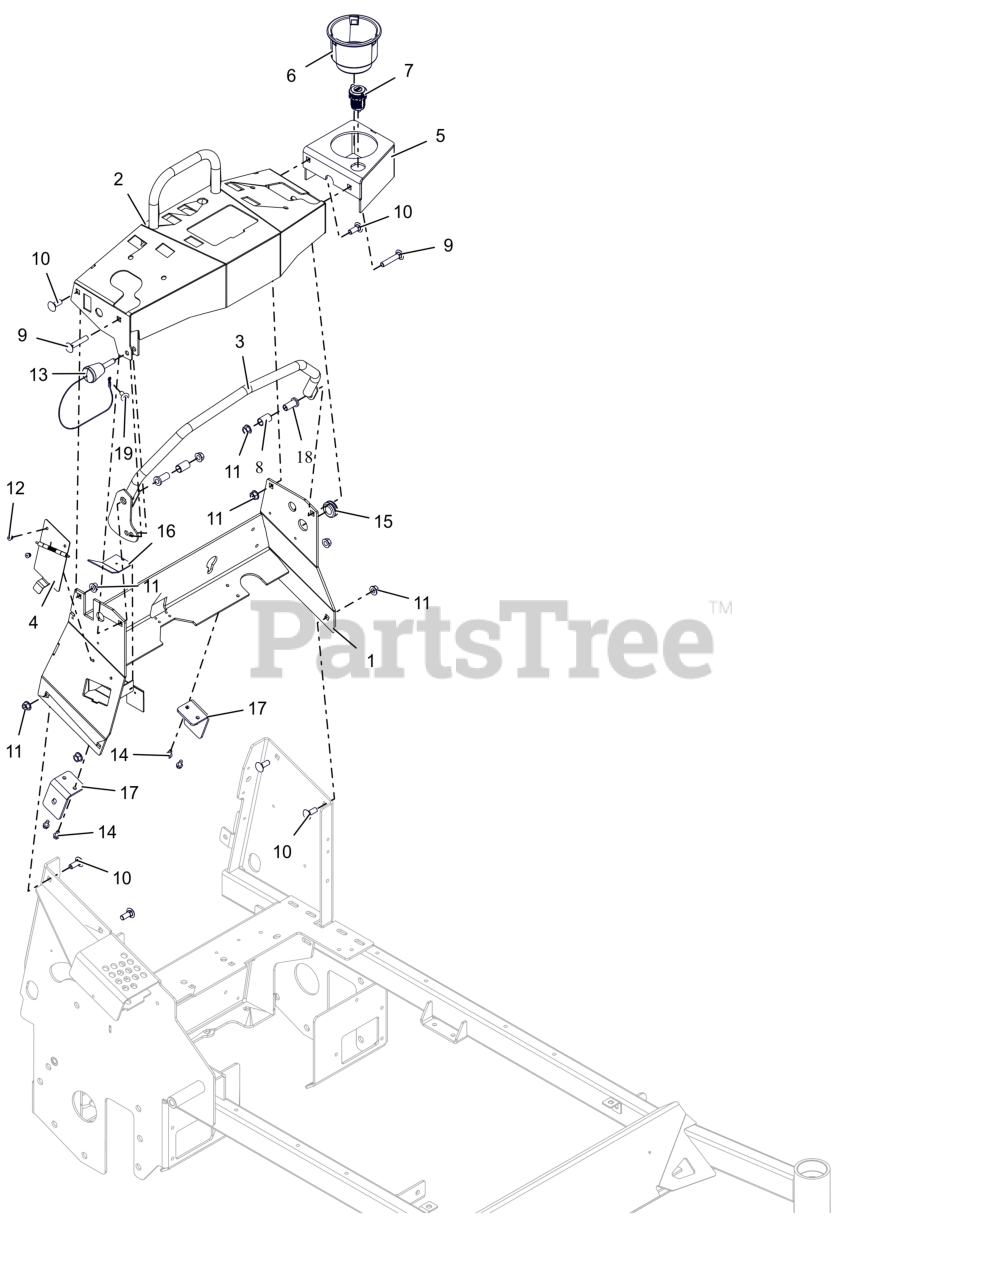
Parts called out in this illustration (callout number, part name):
1	WLDMT- TOWER
2	WLDMT, DASH (ORANGE)
3	WLDMT, CRUISE BAR (BLACK)
4	ASM, CHARGER COVER
5	WLDMT, CUP HOLDER (ORANGE)
6	CUPHOLDER, SNAP-IN 3.75OD
7	USB, DUAL PORT USB-C, 12V BLK
8	BRG, .500 x .625 x1.000
9	BLT, RHSN .38-16X2.00 G5 ZCC
10	BLT, RHSN .38-16X1.00 G5 ZCC
11	NUT-LK-CTR-FLG .375-16 GF ZCC
12	RVT, .1875 AL .063-.250 HD BLK
13	PIN- MAGNETIC .375 X 1.5
14	SCR-TAP .25-20X.50 HWH ZCC
15	GROMMET, RUBBER .688 ID X 1.000 X .500 X 1.313
16	COVER, CHARGER BRACKET (ORANGE)
17	BRKT- DAMPER MTG
18	BSHG, FLANGED
19	XMAS TREE FASTNER-BLACK
